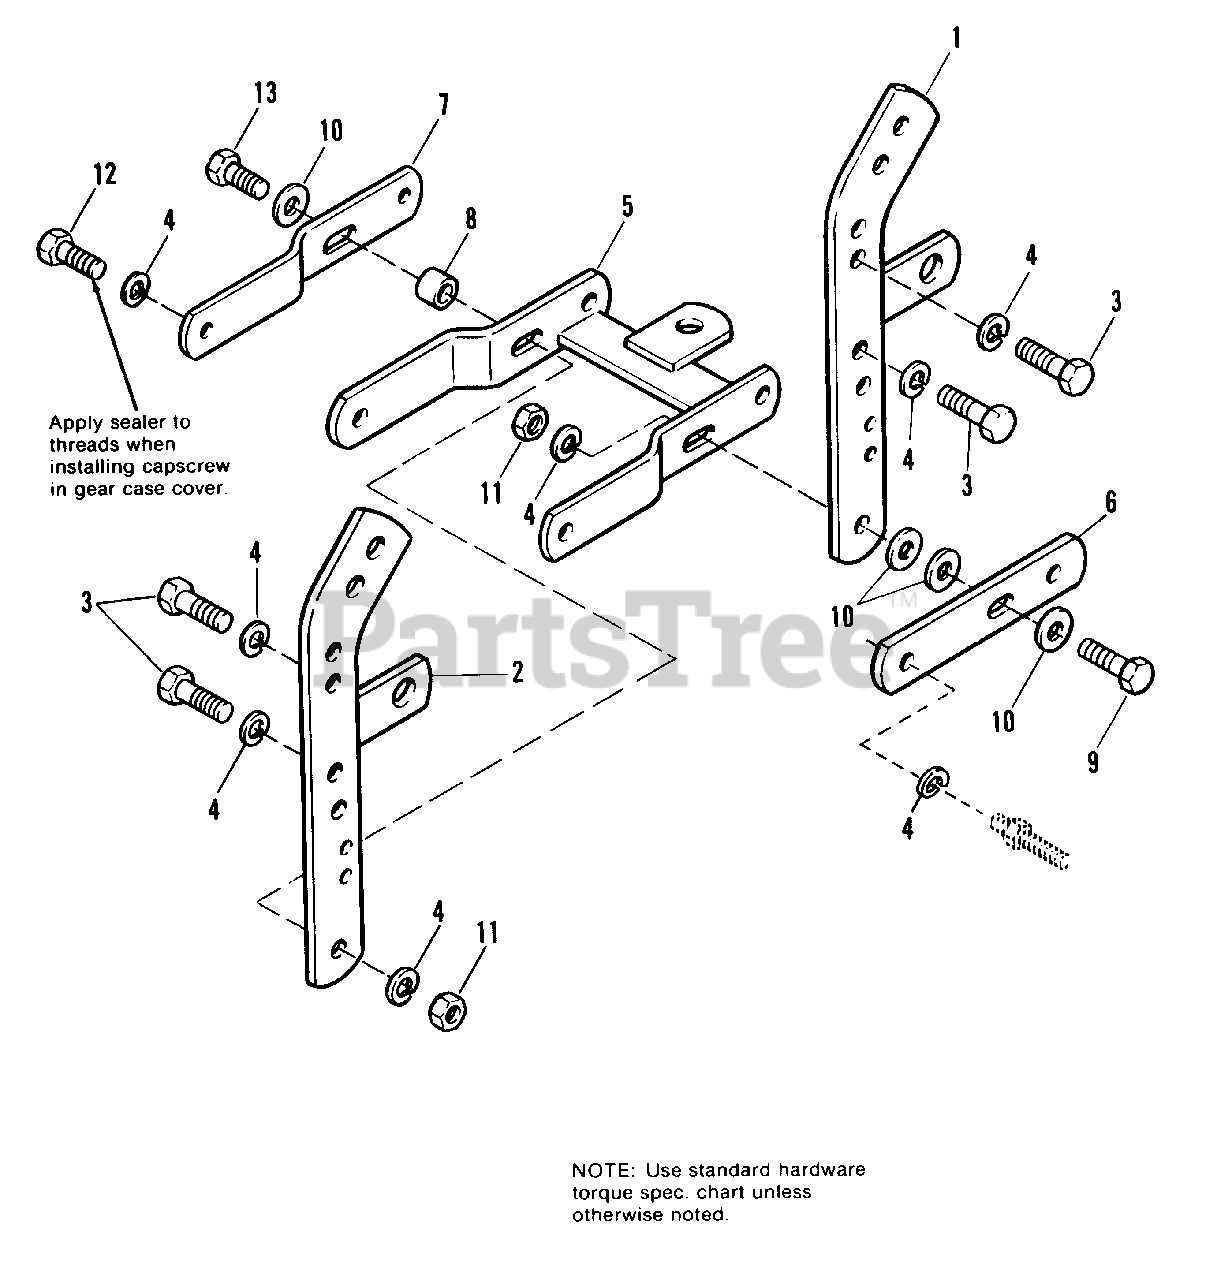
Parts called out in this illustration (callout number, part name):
1	ARM ASSY., LH
2	ARM ASSY.,RH
3	CAPSCREW, Hex Hd., 7/16-14 x 1
4	LOCKWASHER, 7/16
5	DRAW BAR ASSY.
6	BAR, Pull, LH
7	BAR, Draw, RH
9	CAPSCREW, Hex Hd., 7/16-14 x 1-1/4
10	WASHER, 7/16
11	NUT, Hex, 7/16-14
12	CAPSCREW, Hex Hd., 7/16-14 x 1-3/4
13	CAPSCREW, Hex Hd., 7/16-14 x 2-1/4
